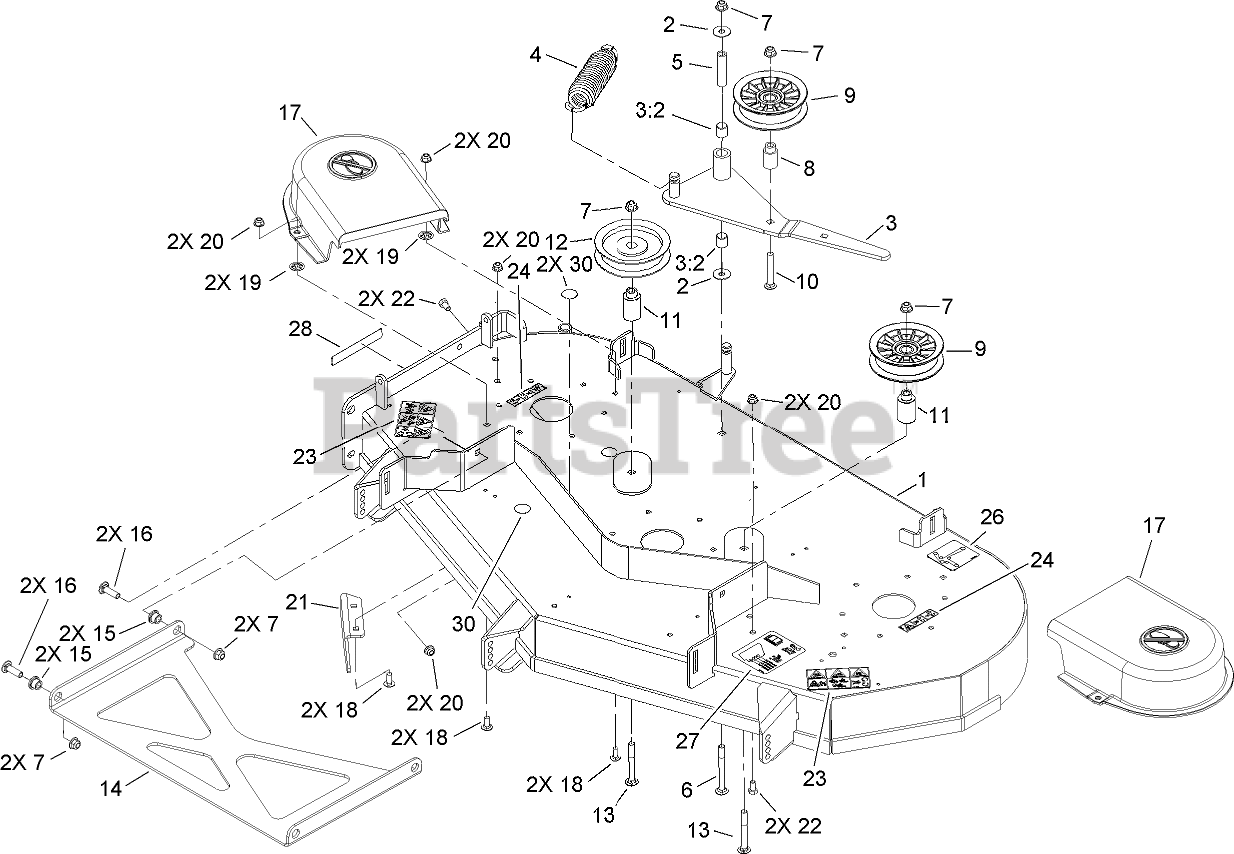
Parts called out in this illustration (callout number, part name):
1	48 INCH DECK ASM
2	WASHER
3	IDLER ARM ASM
3:2	SLEEVE-BEARING
4	Spring-Extension
5	BUSHING-PIVOT, IDLER
6	SCREW-CARR
7	NUT-HF, NI
8	BUSHING-IDLER
9	SHEAVE AND BEARING ASM
10	SCREW-CARR
11	BUSHING-IDLER
12	PULLEY-IDLER
13	BOLT-CARRIAGE
14	STRUT-DECK
15	SPACER-STRUT
16	SCREW-CARR
17	SHIELD-BELT
18	SCREW-CARR
19	RING-RETAINING
20	NUT-HF, NI
21	BAFFLE-DISCHARGE
22	SCREW-HH
23	DECAL-DANGER
24	DECAL-WARNING, BELT SHIELD
26	DECAL-BELT ROUTING
27	DECAL-ROLLER, ANTI-SCALP
28	DECAL-DANGER
30	DECAL-COVER, HOLE
